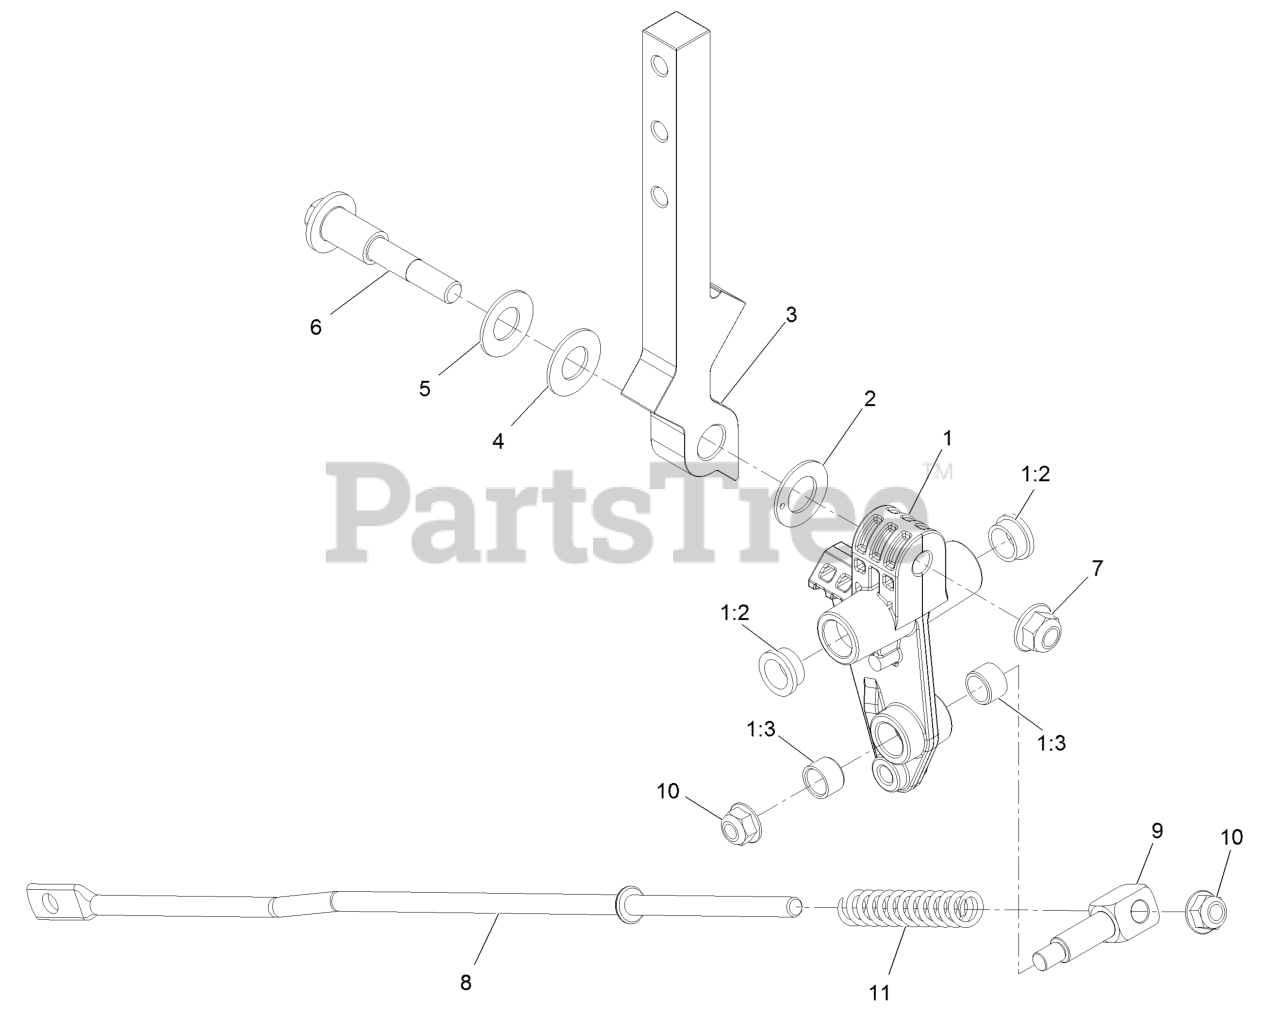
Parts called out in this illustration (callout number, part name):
1	Control Arm ASM
1:2	Bushing-Pm
1:3	Bushing-Sleeve
2	Washer, Friction
3	Arm-Control
5	Washer-Belleville
6	Bolt-Pivot
7	Nut-Nyloc 3/8-16 Flg
8	Link-Control
10	Nut-Nyloc 5/16-18 Flg
11	Spring-Return, Neutral
